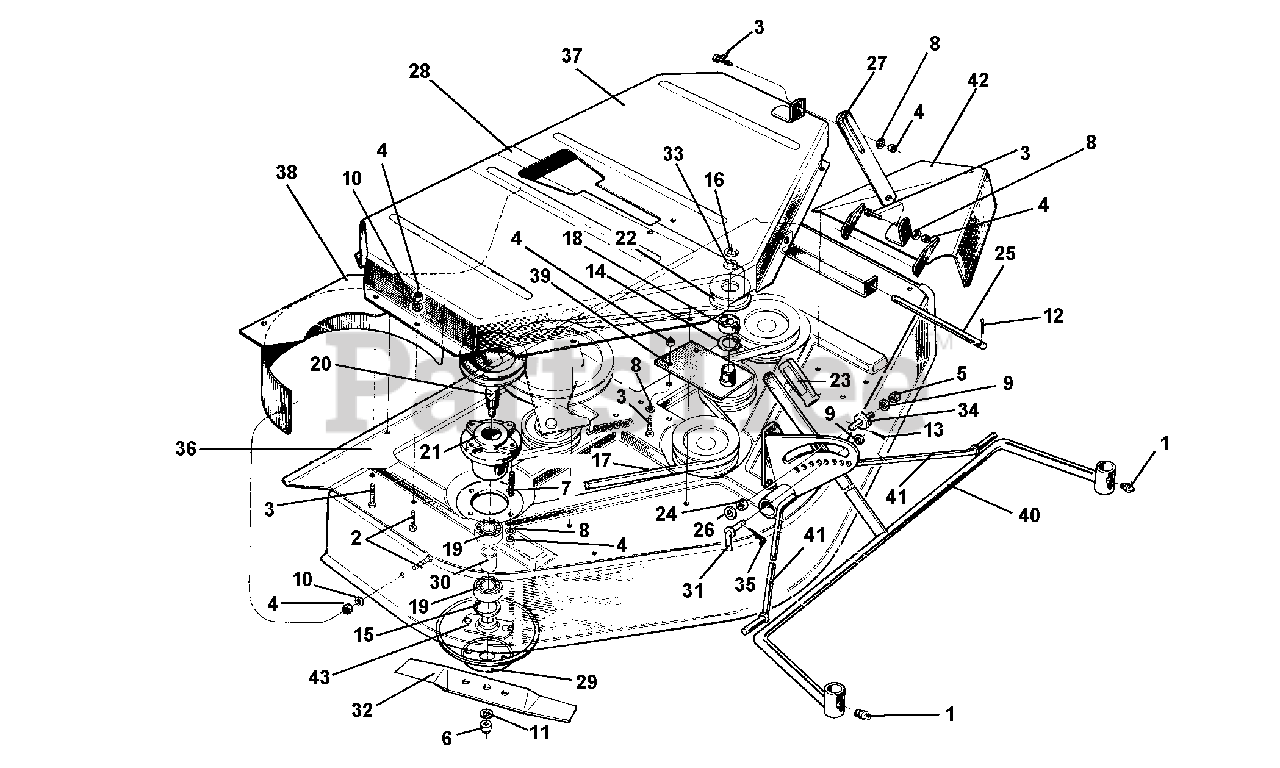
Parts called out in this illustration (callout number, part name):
1	LUBRICATOR M10
2	SCREW M8 X 16
3	SCREW M8 X 20
4	NUT, SELF LOCKING M8
5	NUT, SELF LOCKING M10
6	NUT, SELF LOCKING M12 LOW
7	STUD M8 X 38 X 14 X 20
8	WASHER, FLAT 8.4
9	WASHER P10.5 X 18
10	WASHER, LOCK 8.4
11	WASHER, LOCK 13
12	PIN, COTTER A 3 X 20 UNI 1336
13	PIN, COTTER 4 X 25
15	CIRCLIP, INTERN D 52
16	CIRCLIP, EXTERN D 17
17	V BELT A 78
18	BEARING 17 X 40 X 12 6203 2RS
19	BEARING 25 X 52 X 15 6205 2RS ST
20	SHAFT WITH PULLEY
21	CASING, BLADE HOLDER
22	GUIDE PULLEY
24	BUSH, CONTROL
25	PIN, COUPLING
26	WASHER 12.5 X 34 X 5
28	HALF PROTECTION, RIGHT
29	KNIFE GUEARD
31	ADJUSTMENT PIN
32	BLADE, LAWN MOWER L 362
34	PIN, ADJUSTMENT LEVER
36	DECK, LAWN MOWER
37	HALF PROTECTION, LEFT
38	BAFFLE, REAR
40	AXLE, WHEELS
42	DOOR, LATERAL
43	BLADE HOLDER HUB
